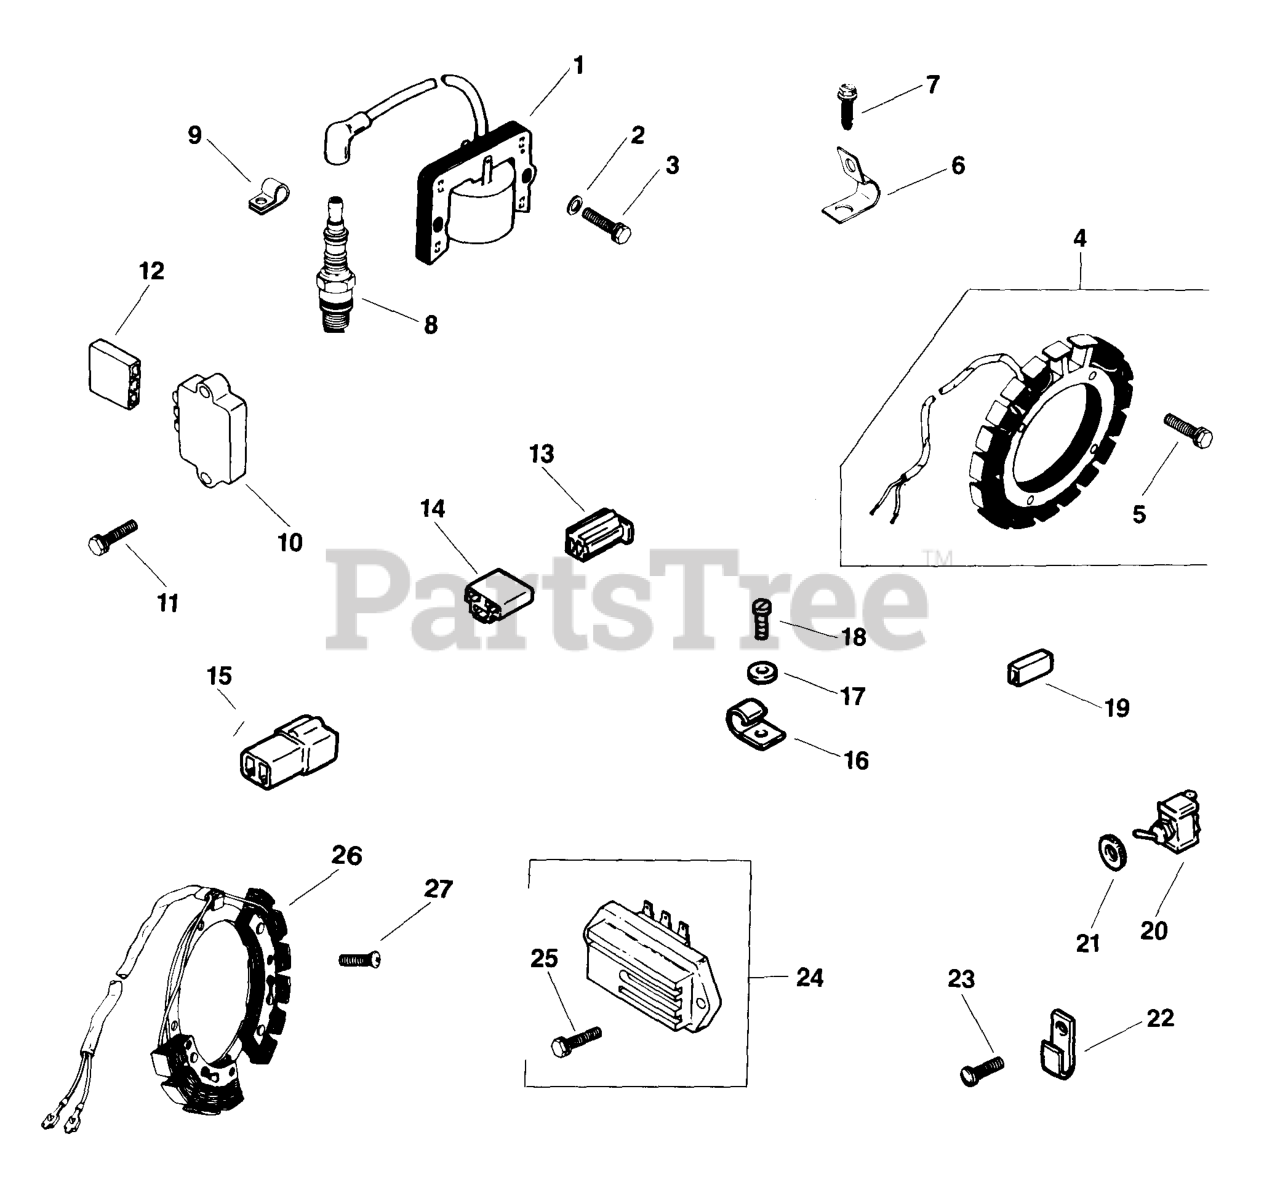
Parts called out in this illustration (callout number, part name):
1	MODULE - USE 47 584 02
2	WASHER, FLAT 3/16"
3	SCREW - USE X-67-51-S
4	KIT, 15 / 20 AMP STATOR
5	SCREW, WSH HD TAP #10-24X3/4" USE 25 086 97-S
7	SCREW, WASHER HD TAP #8-32X3/8" USE 25 086 99-S
10	KIT - USE 25 755 03
11	SCREW
12	CONNECTOR, BODY (KM)-USE 25 155 41-S
25	SCREW, SEMS 1/4-20X5/8" USE 25 086 539-S
4751843-S	LEAD
